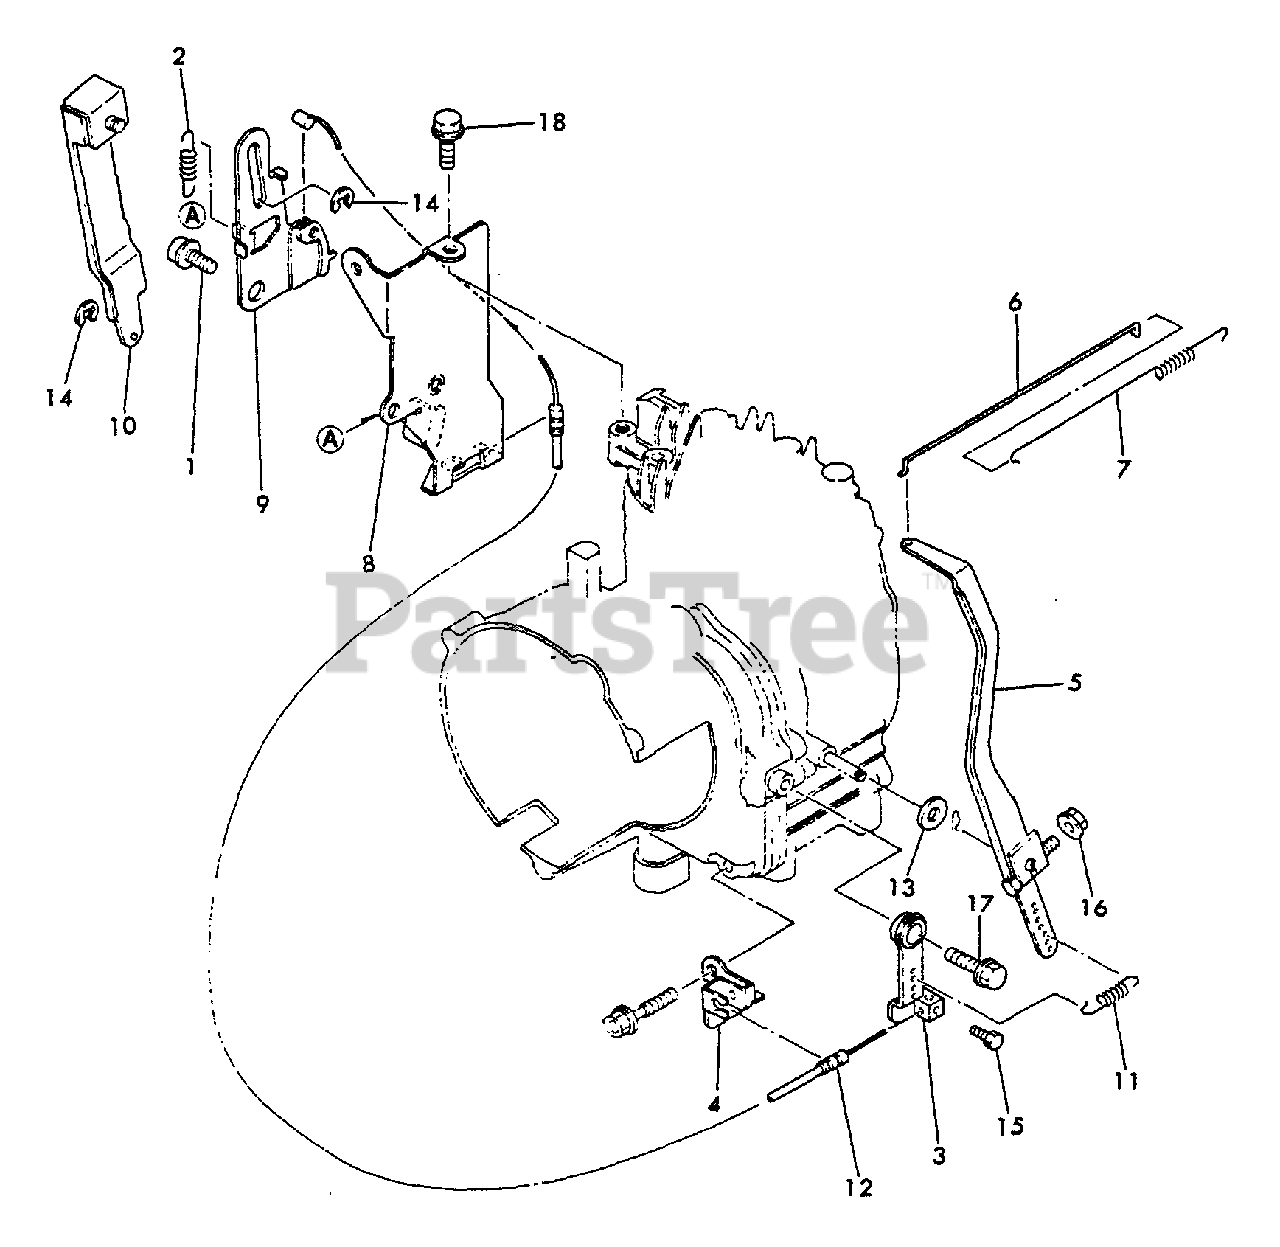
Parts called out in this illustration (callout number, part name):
1	SCREW - 6X10
2	SPRING, REGULATOR
3	HANDLE ASSY
4	WIRE HOLDER
5	LEVER, GOVERNOR
6	LINK, THROTTLE
7	SPRING
8	BRACKET, LEVER
9	LEVER, CONTROL
10	LEVER, CONT. SHIFT
11	SPRING, CONTROL LEVER
12	THROTTLE CABLE ASSY
13	WASHER
14	RING, RETAINING - 5
15	BOLT - 4X8 -- PLATED
16	NUT - 6 -- FLANGE
17	BOLT - 6X8 -- PLATED
18	BOLT - 6X8 -- PLATED
